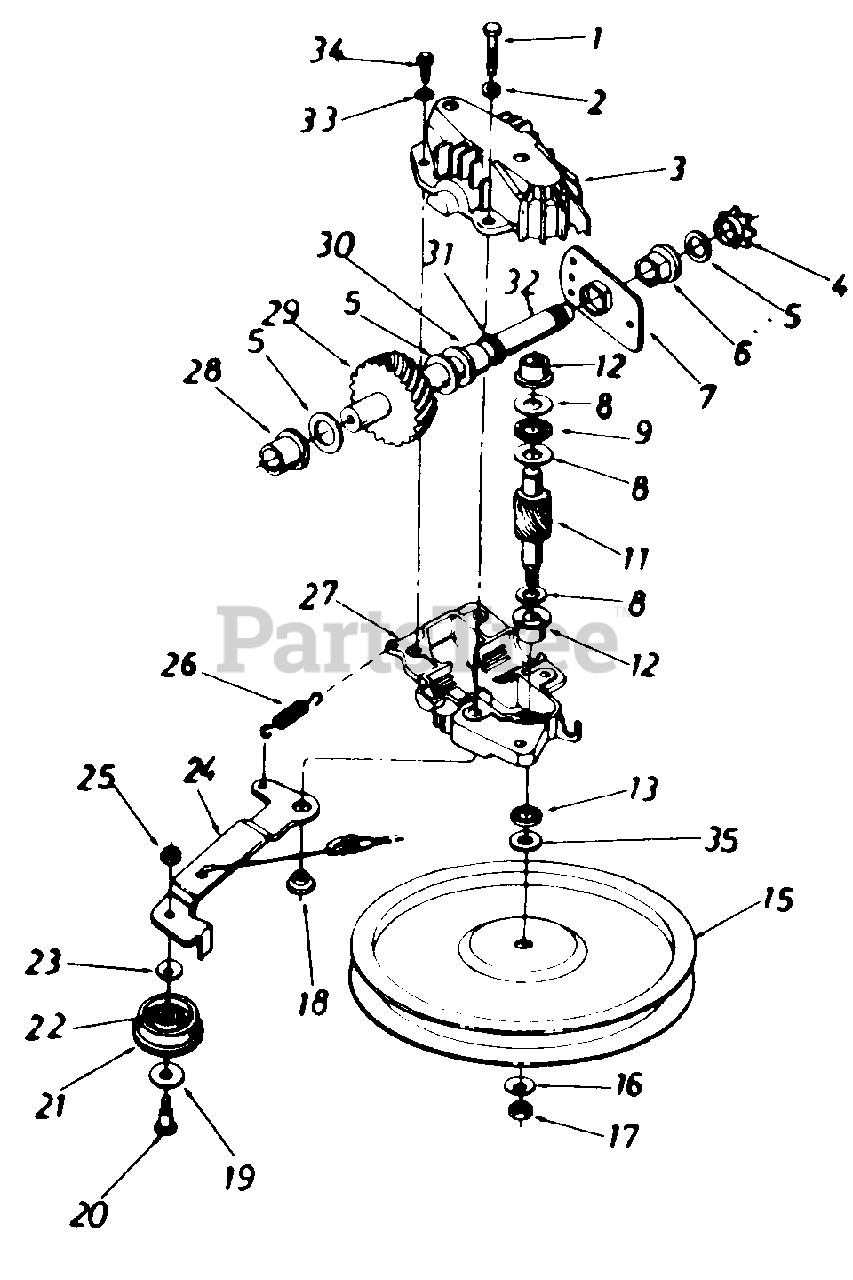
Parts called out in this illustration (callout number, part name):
1	Hex Bolt 1/4-20 x 1.25" Lg. w/Patch
2	L-Wash. 1/4" I.D.
3	Upper Hsg. Half
4	#48 Sprocket 7 Tooth x 1/2 Pitch
5	Fl-Wash. 5/8" I.D. x .030
6	Hex Flange Brg. .631" I.D.
8	Thrust Wash. .382" I.D. x .70" O.D.
9	Thrust Bearing .375" I.D. x .812" O.D.
11	11 Tooth Helical Gear
12	Flange Bearing
15	Fl-Pulley 5.06" I.D.
16	Bell-Wash. .265" I.D. x 75"
17	Hex Nut 1/4-28 L.H. Thd.
18	Shld. Spacer .375" Dia. x .170
19	Fl-Wash. .390" I.D. x 1.0"
20	Shld. Bolt .375" Dia. x .40"
21	Fl-Idler Plastic 1.50" Dia.
22	Needle Brg. .375" x .31"
23	Bell-Wash. .265" I.D. x 75"
24	Idler Brk't. Ass'y.
25	Hex Patch L-Nut 1/4-28 Thd.
26	Extension Spring 1.12" Lg.
27	Lower Hsg. Half
28	Flange Bearing .56 Dia.
29	33 Tooth Helical Gear
30	Flange Bearing .629 Dia.
31	Oil Seal .625 Dia.
32	Gear Sprocket Shaft
33	L-Wash. #10 I.D.
34	Hex B-Tap Scr. #10 x .62"
35	Hex Washer .26 x .88
